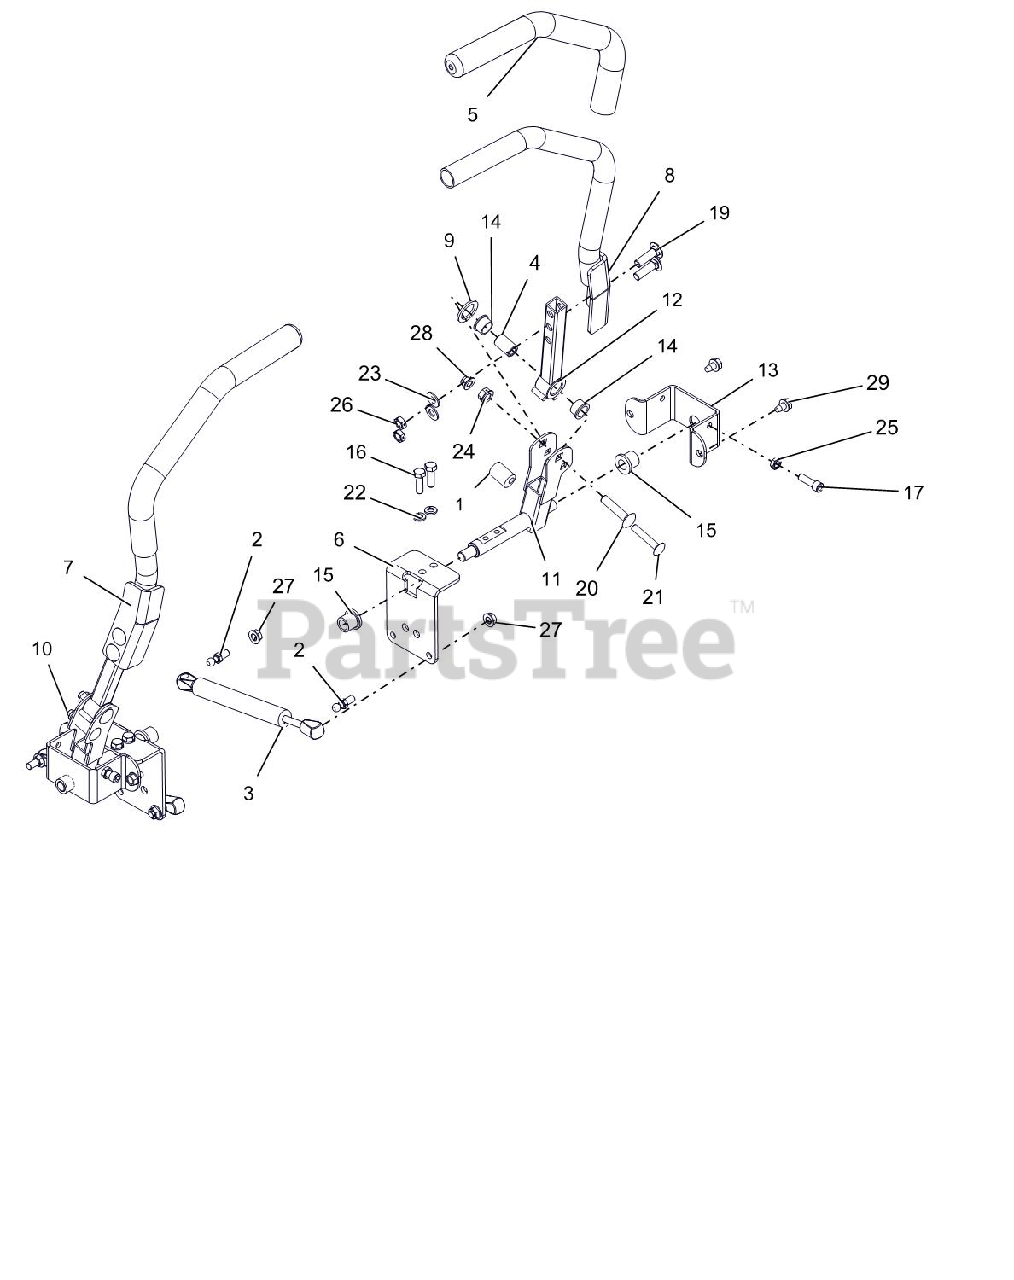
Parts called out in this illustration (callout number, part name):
1	BSHG,ECCEN .328X.750X1.01 PM
2	STUD- BALL
3	DAMPER, STABILUS
4	SPACER, .375X.625X.970 (PM)
5	GRIP, HANDLEBAR 15" FOAM
6	BRKT, STEEERING
7	WLDMT, STEERING HANDLE RH
8	WLDMT, STEERING HANDLE LH
9	WASHER, FRICTION .875X1.25X.10
10	WLDMT,STEERING ARM LOWER RIGHT
11	WLDMT,STEERING ARM LOWER LEFT
12	WLDMT, UPPER CONTROL ARM
13	BRKT, STEERING
14	BSHG-FLG, .625X.75X.450X.875
15	BSHG-FLG .515X.750X.745X1.00NY
16	BLT-HEX .31-18X1.00 GR8 YWZC
17	SCR, SKH .312-18X1.00 G8 SS
19	BLT,RHSSN .38-16X1.25 G5 BFP
20	BLT,RHSSN .38-16X1.75 G5 BFP
21	BLT,RHSSN .31-18X1.75 G5 BFP
22	@WSHR-LK .31X.078 REG YWZC
23	@WSHR-FL-STL.406X.812X.065 YWZ
24	NUT-LK-CTR-FLG .38-16 YWZC
25	NUT- JAM .312-18 YWZC
26	@NUT-LK-CTR-JAM .375-16 YWZC
27	@NUT-LK-TOP-FLG .31-18 YWZC
28	@NUT-LK-NYL-FLG .31-18 YWZC
29	@SCR-TAP .31-18X.50 HWH TR YWZ
